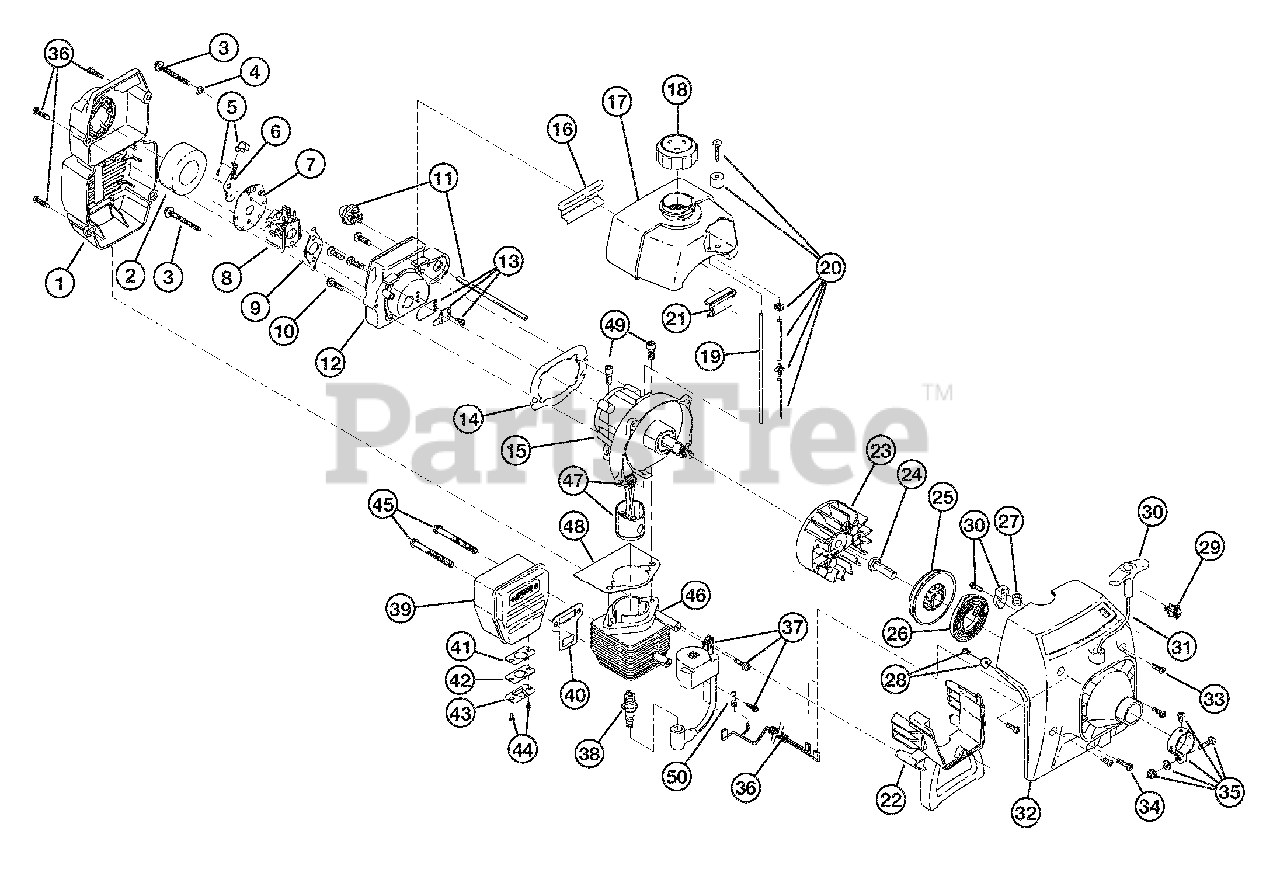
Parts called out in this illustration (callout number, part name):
1	Air Cleaner/Muffler Cover Assembly
2	Air Cleaner Filter
3	Carburetor Mounting Screws
4	Wavey Washer
5	Choke Knob & Screw
6	Choke Lever Assembly
7	Choke Lever & Plate
8	Carburetor Assembly
9	Carburetor Gasket
10	Carb Mount Screw
11	Primer and Hose Assembly
12	Carburetor Mount Assembly
13	Reed Assembly
14	Carburetor Mount Gasket
15	Crankcase Service Assembly
16	Rear Mounting Pad
17	Fuel Tank Assembly
18	Fuel Cap Assembly
19	Fuel Return Line
20	Fuel Line Assembly
21	Front Mounting Pad
22	Shroud Extension and Stand
23	Flywheel Assembly
24	Square Nut Drive
25	Recoil Pulley
26	Recoil Spring
27	Rope Guide
28	Pulley Retainer Assembly
29	Switch Assembly
30	Pull Handle
32	Starter Housing Assembly
33	Housing Screw
34	Cover Screw
35	Upper Clamp Assembly
36	Wire Lead
37	Module Assembly
38	Spark Plug
39	Muffler Assembly
40	Exhaust Gasket
41	Spark Arrestor
42	Spark Arrestor Plate
43	Spark Arrestor Hood
44	Screw
45	Muffler Mounting Bolt Assembly
46	Cylinder Assembly
47	Piston & Rod Assembly
48	Cylinder Gasket
49	Cylinder Bolt
50	Ground Tab
